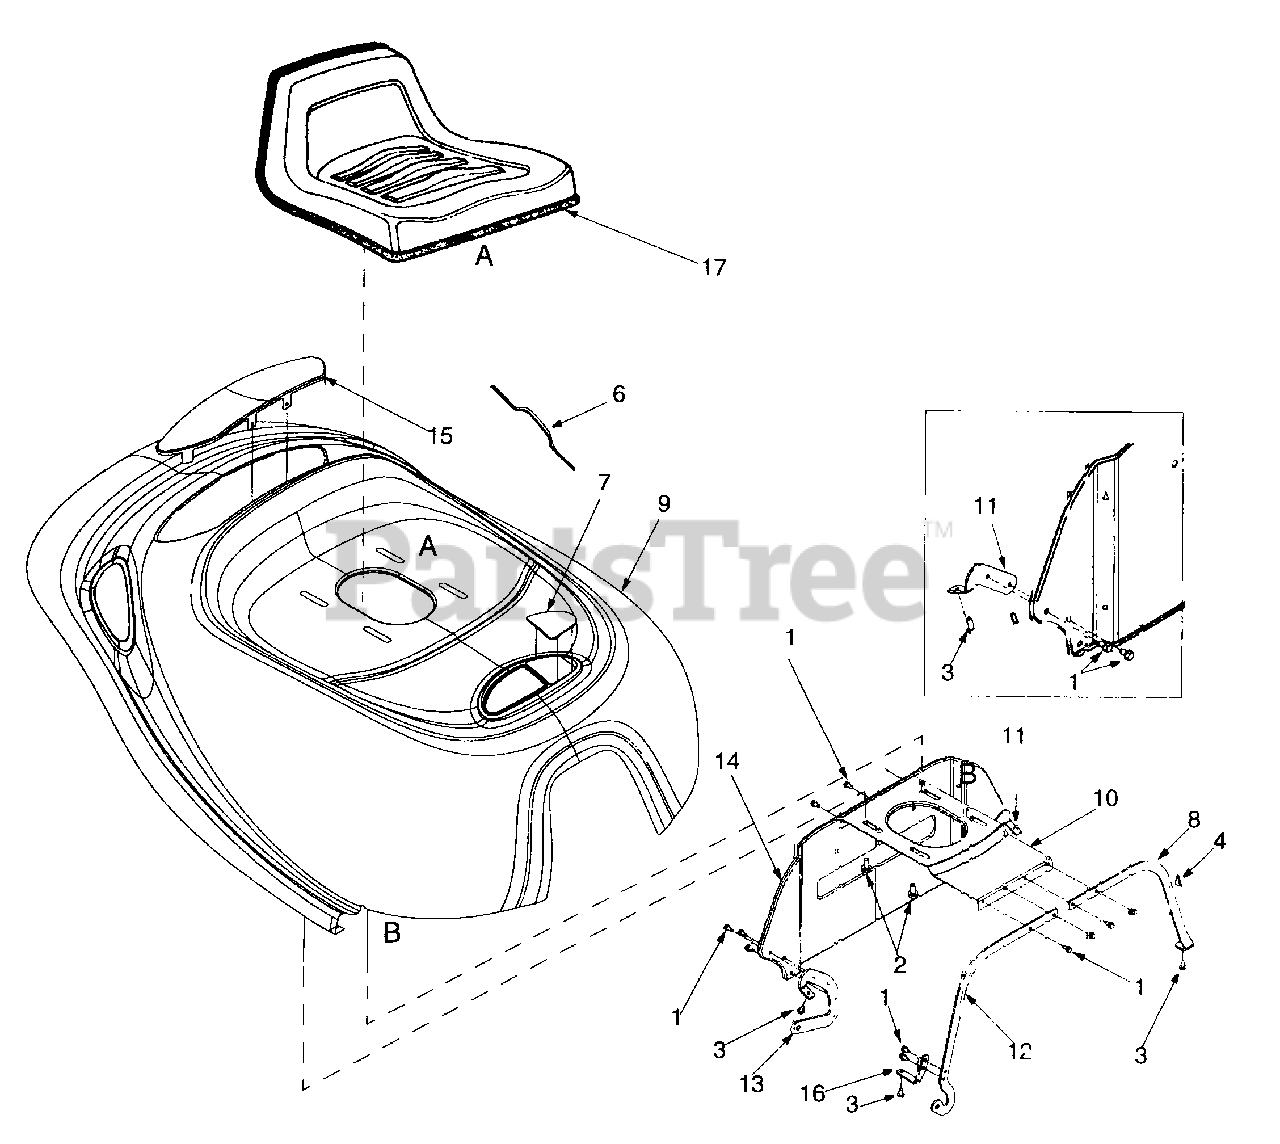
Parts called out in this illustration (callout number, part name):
1	Hex Hd. TT Screw 1/4-20 x 0.5
2	Hex Washer Hd. TT Screw 3/8-16 x 0.62
3	Torx Head AB screw 1/4-14 x 0.625
4	Rod End Grip
6	Trim Strip
7	Grass Bag Lens
8	Bracket Reinforcement: Hood
10	Plate: Hood
11	Hood Bracket
12	Hood Bracket: Reinforcement
17	Seat
